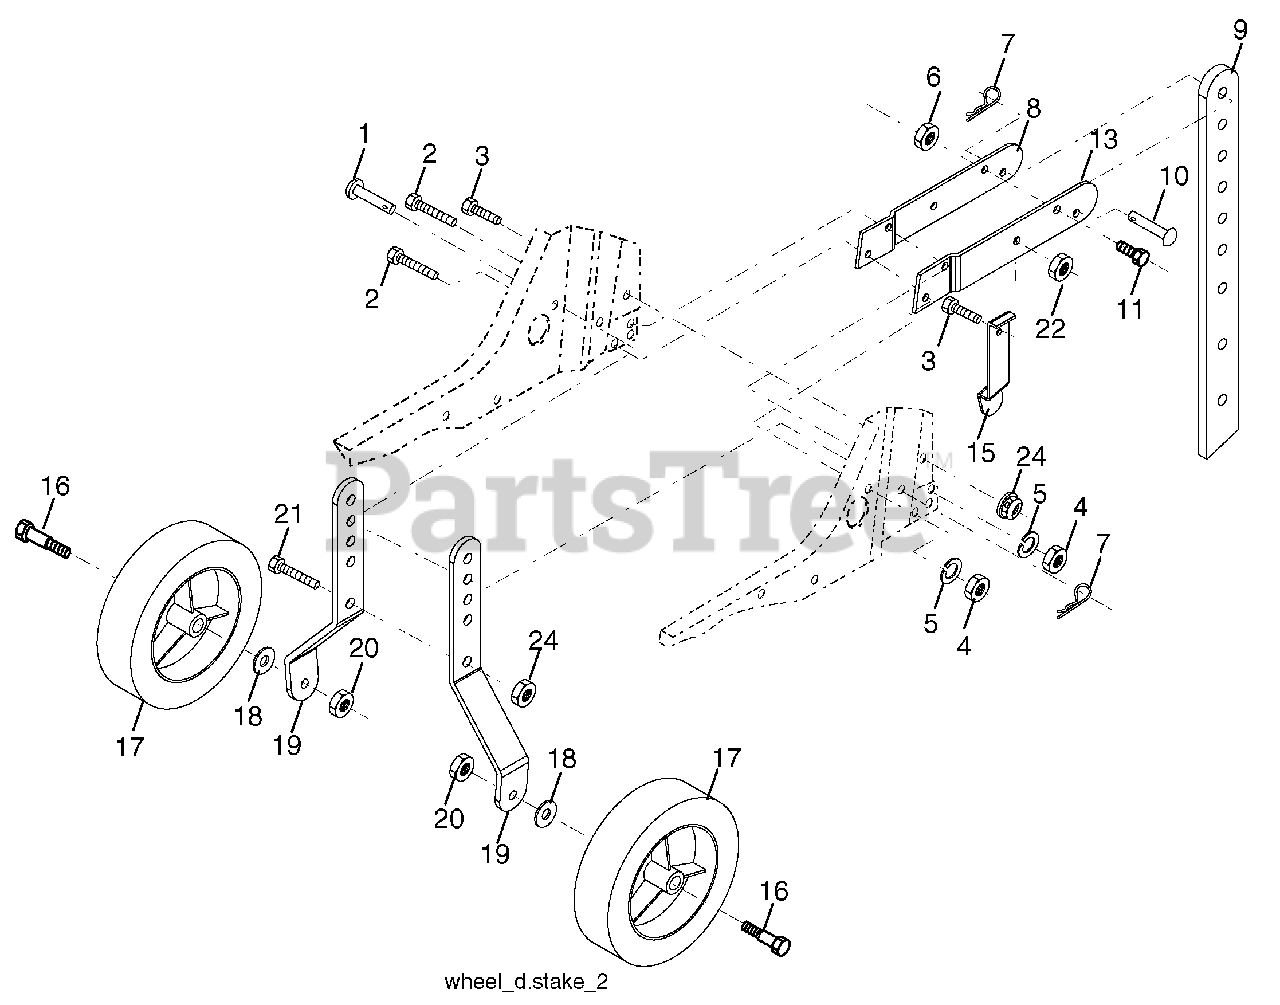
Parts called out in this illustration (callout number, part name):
1	Pin, Clevis
2	Bolt, Hex 5/16-18 x 1-1/4
3	Bolt, Hex 5/16-18 x 3/4
4	Nut, Hex 5/16-18
5	Washer, Lock 5/16
6	Locknut, w/washer 3/8-16
7	Clip, Hairpin
8	Support, Depth Stake, R.H.
9	Stake, Depth
10	Pin, Clevis
11	Bolt, Hex, Fin 3/8-16 x 1-3/4
13	Support, Depth Stake, L.H.
15	Spring, Stake
16	Bolt, Shoulder
18	Washer 13/32 x 13/16 x 11 Ga.
19	Bracket, Wheel
20	Locknut, Crown 3/8-16
21	Bolt, Hex 5/16-18 x 1
22	Locknut, w/insert 5/16-18
24	Nut Lock Hex Flange
